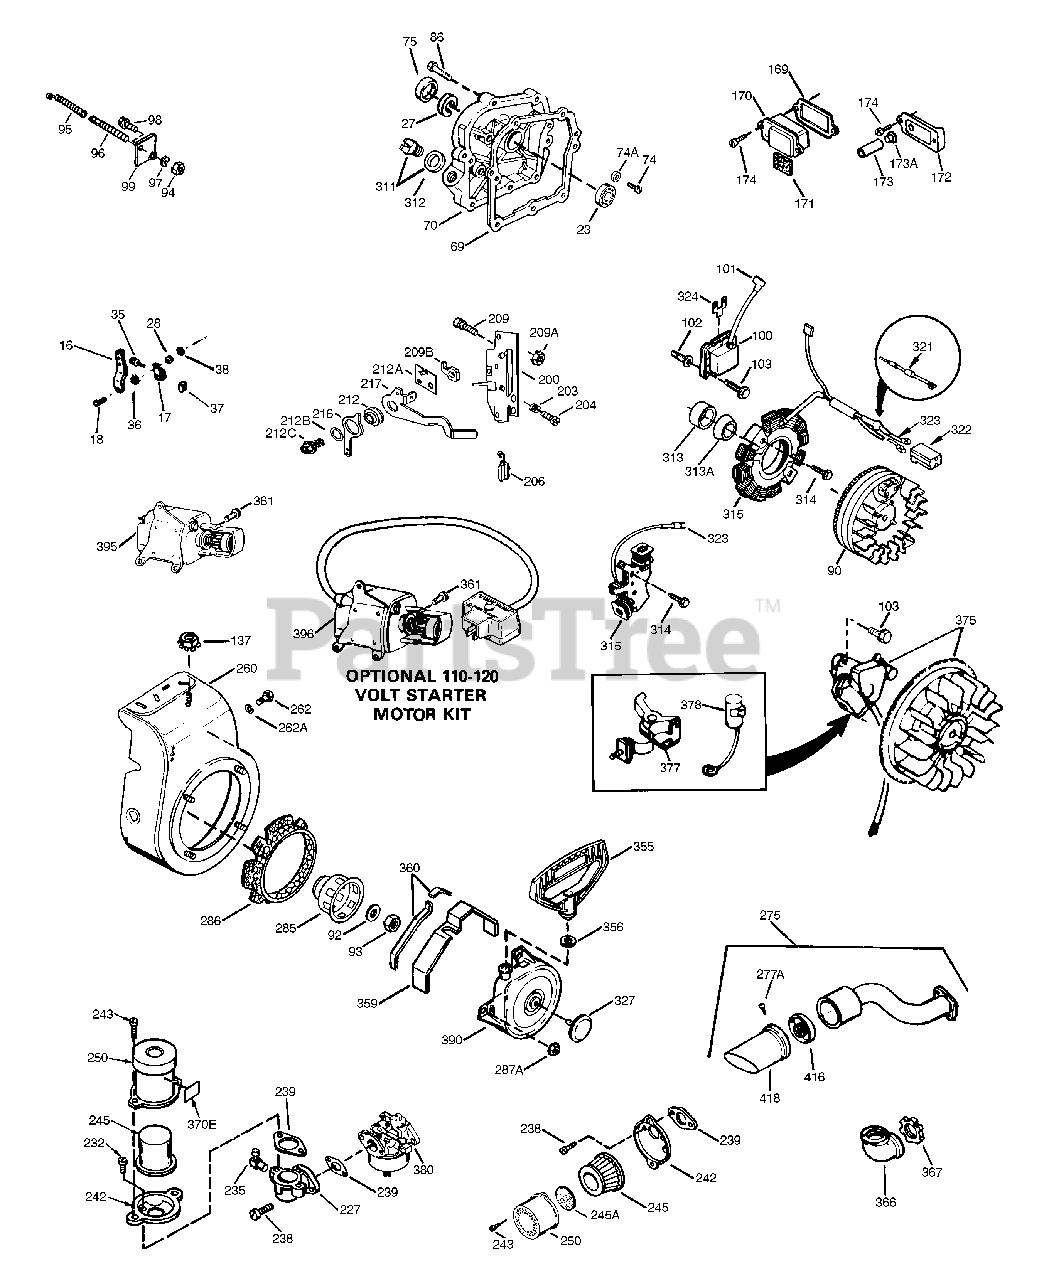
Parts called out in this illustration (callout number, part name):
16	Governor Lever
17	Governor Lever Clamp
18	Screw, 8-32 x 5/16"
69	* Cylinder Cover Gasket
70	Cylinder Cover (Incl. 75 thru 83)
75	Oil Seal
84	Retaining Ring
86	Screw, 1/4-20 x 1-1/4"
90	Flywheel (W/Ring Gear)
92	Belleville Washer
93	Flywheel Nut
100	Solid State Ignition
101	Spark Plug Cover
102	Solid State Mounting Stud
103	Screw, Torx T-15, 10-24 x 1"
129	Screw, 5/16-18 x 1-1/2"
131	Screw, 5/16-18 x 2"
169	* Valve Cover Gasket
170	Breather Body
171	Breather Element
172	Valve Cover
173	Breather Tube
174	Screw, 10-24 x 1/2"
200	Control Bracket Incl. 203,204,206,209 & 209A
203	Compression Spring
204	Screw, 5-40 x 7/16"
206	Terminal
209	Screw, 8-32 x 1/2"
209A	Lock Nut, 8-32
260	Blower Housing
261	Screw, 1/4-28 x 7/16"
275	Muffler (Incl. 274)
285	Starter Cup
327	Starter Plug
335	Carburetor Cover
355	Starter Handle (Mitten Grip) also ava ilable in Packaged Part #740053B
380	Carburetor (Incl. 184)
390	Rewind Starter
396	Electric Starter Motor (110 Volt) Opt ional)
